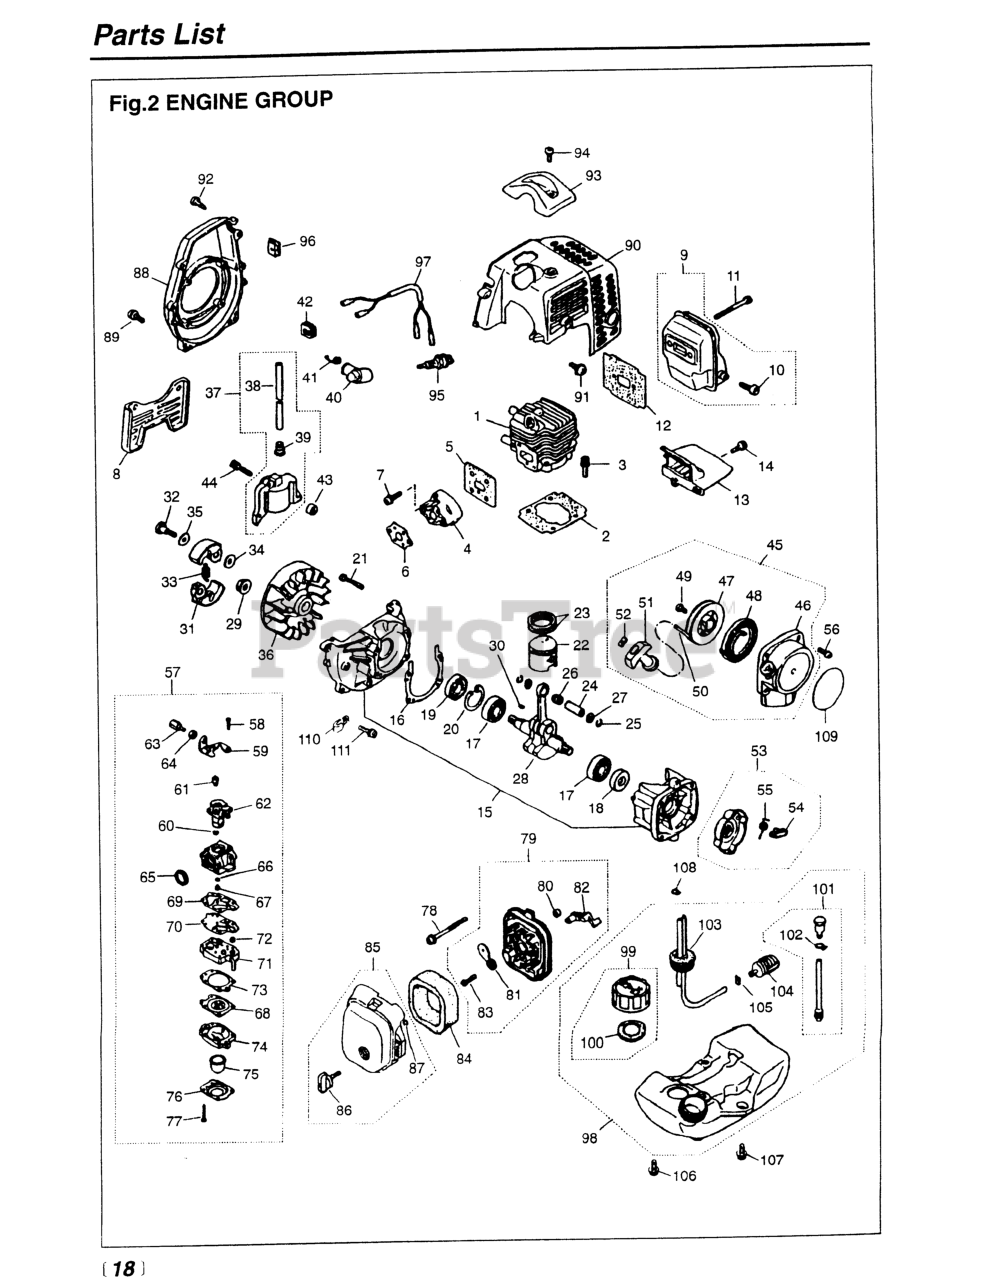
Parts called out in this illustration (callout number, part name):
1	CYLINDER
3	BOLT, M5 X 22
4	INSULATOR (USE -13163)
7	SCREW, M5X20 (RPLS.1400-75510)
8	STAND
9	MUFFLER ASSY (RPLS 5501- )
11	BOLT, M5 x 50
12	GASKET, MUFFLER
14	SCREW, M4 X 16
15	CRANKCASE
17	BEARING
18	SEAL, OIL (RPLS 1100-21210)
19	SEAL, OIL (RPLS 1140-21220)
20	RING, SNAP, M28 x 1.2
21	BOLT, M5 X 30
22	PISTON
23	RING, PISTON
24	PIN, PISTON
25	RING, SNAP (RPLS 1101-41320)
27	WASHER
28	CRANKSHAFT (RPLS 1850-42000)
30	KEY
31	SHOE (RPLS 1100-51114)
32	BOLT
33	SPRING, CLUTCH (RPLS-51220)
34	WASHER, FLAT (USE 182303)
37	COIL ASSY (RPLS 5500-71200)
38	CORD
39	CAP
41	SPRING
42	GROMMET
43	SPACER (RPLS -71260)
44	BOLT
45	RECOIL ASSEMBLY
46	CASE
47	REEL
48	SPRING, SPIRAL
49	SCREW (RPLS -75150)
51	KNOB
52	PLATE, STOPPER
53	PULLEY ASSY (RPLS -75210)
54	RATCHET (RPLS 1850-75220)
55	SPRING, RETURN
56	SCREW, M4 X 16
57	CARBURETOR (WYJ-117)
58	SCREW
60	RING
61	SWIVEL
62	VALVE ASSY
63	SCREW, CABLE ADJUSTER
64	NUT, CABLE ADJUSTER
65	RING, PACKING
66	RING, O
68	DIAPHRAGM (USE 4810-81260)
69	GASKET, PUMP
70	DIAPHRAGM
71	BODY, PUMP
73	GASKET, DIAPHRAGM
74	BODY, PURGE
75	PUMP, PRIMING
76	COVER, PUMP
77	SCREW
78	SCREW, M5 X 55
79	BODY-A (RPLS -82101)
80	SLEEVE
81	PLATE, CHOKE (RPLS-82130)
82	LEVER, CHOKE
83	SCREW (REPLACES 50030272)
84	ELEMENT
86	KNOB (RPLS -82220)
87	RING
88	COVER, FAN (RPLS-31110)
89	SCREW, M5X20 (RPLS.1400-75510)
91	SCREW, M5 x 12
92	SCREW, HOUSING
93	GUARD, PLUG
94	SCREW,M5 X 14 (RPLS 1400-15510
97	CORD COMP (RPLS -73200)
99	CAP (RPLS -85200)
100	PACKING
102	CLIP
103	PIPE COMPLETE
104	FILTER (RPLS 1850-85300)
105	CLIP (REPLACES 2841-31280)
106	SCREW
107	SCREW W/ WASHER
108	CLIP
110	CLAMP
111	SCREW,M5 X 14 (RPLS 1400-15510
